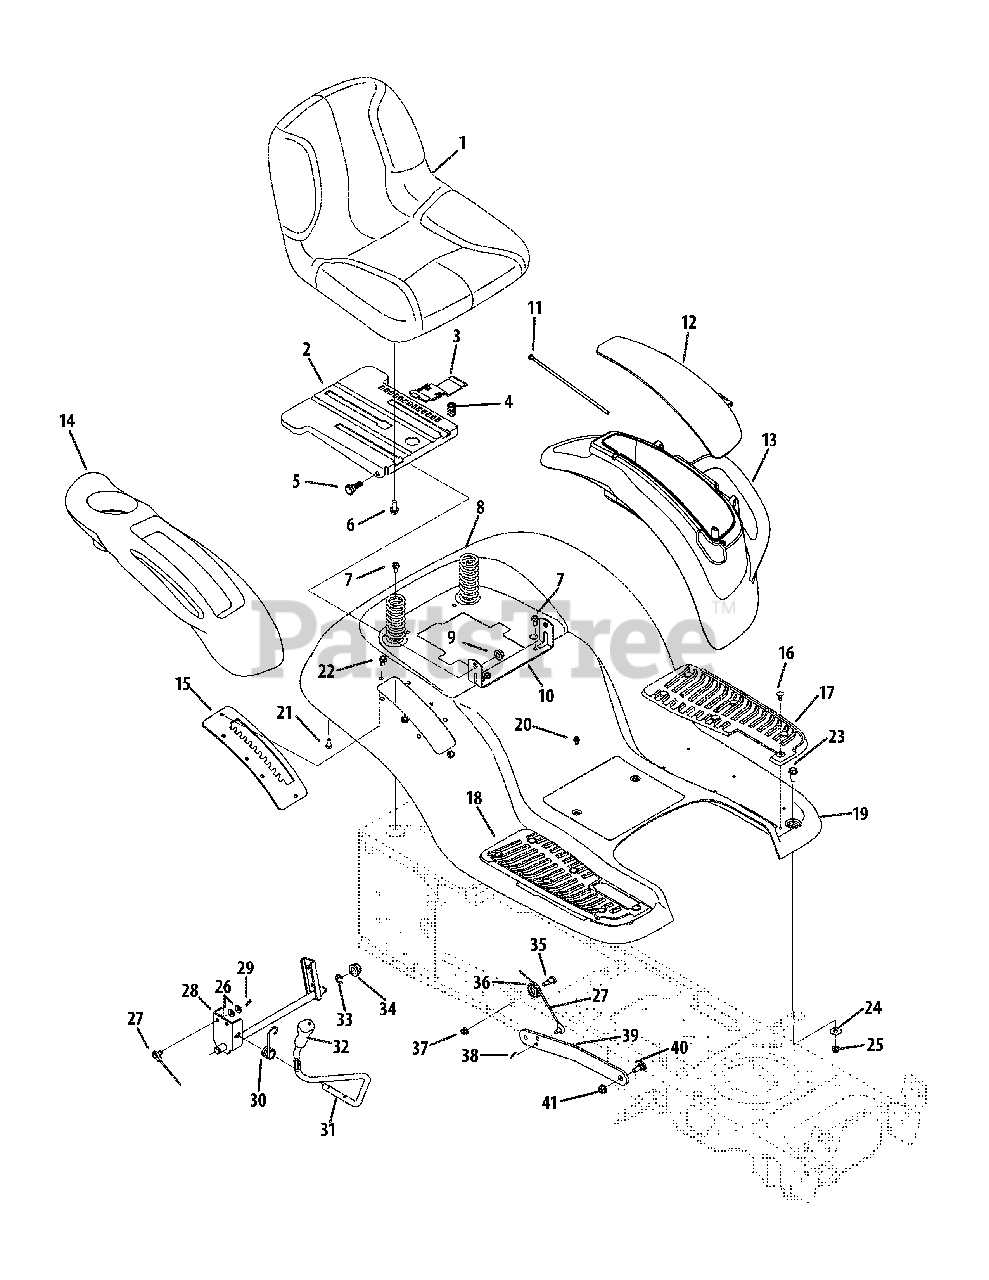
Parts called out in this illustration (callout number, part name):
1	High-Back Chair
2	Seat Mounting Bracket
3	Seat Adjustment Lever
4	Compression Spring, .68 x 1.065 x .055
5	Shoulder Screw, 5.16-18 x .437 x .268
6	Hex Flange Bolt, 3.8-16 x .875
7	Hex Washer Screw, 5.16-18 x .750
8	Compression Spring, 1.71 x 3.735 x .238
9	Flange Lock Nut, 5.16-18
10	Seat Pivot Bracket
11	Door Pin LH Pod
12	Fender Cover Door
13	Fender Cover, LH
14	Fender Cover, RH
15	Lift Adjustment Bracket
16	Ratchet Clip
17	Foot Pad, LH
18	Foot Pad, RH
20	Hex Washer Screw, 1.4-20 x .500
21	Hex Washer Screw, 1.4-15 x .750
22	Hex Washer Screw, 5.16-18 x .750
23	Hex Washer Screw, 5.16-18 x .750
24	Flat Washer, .344 x 1.0 x .063
25	Flange Lock Nut, 5.16-18
26	Washer, .401 x .870 x .063
27	Lift Cable
28	Lift Shift Assembly
29	Cotter Pin, .072 x 1.13
30	Torsion Spring
31	Lift Handle
32	Handle Grip
33	E-Type Ring
34	Hex Flange Bearing
35	Shoulder Screw, 5.16-18 x .437 x .470
36	Cable Roller Pulley
37	Flange Lock Nut, 5.16-18
38	Bow-Tie Cotter Pin
39	Lift Arm
40	Shoulder Bolt, 3.8-16 x .500 x .270
41	Flange Lock Nut, 3.8-16
